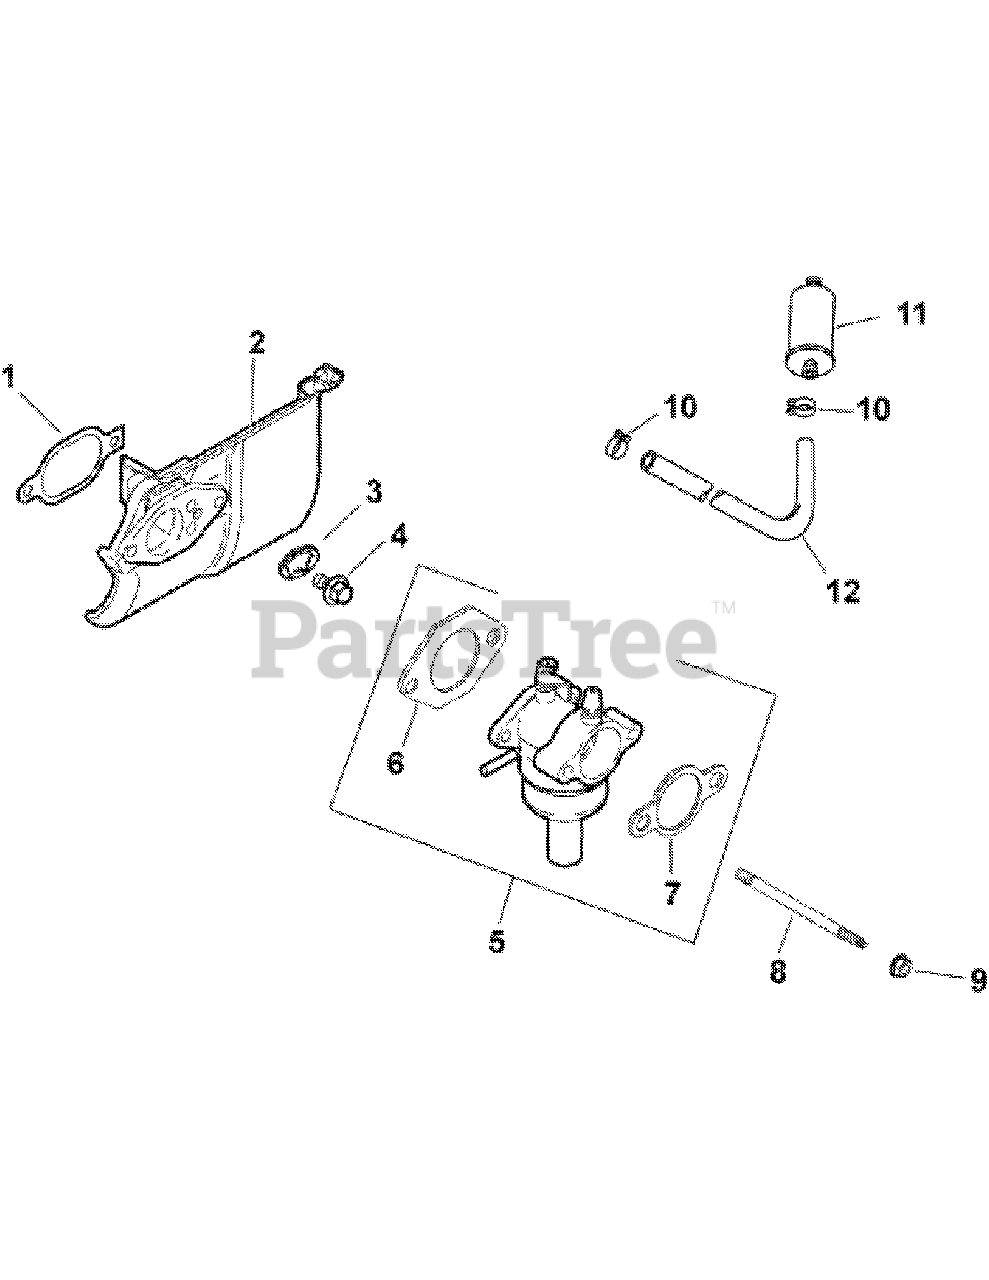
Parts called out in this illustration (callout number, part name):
2	KIT
3	WASHER, INT TOOTH LOCK 1/4"
4	SCREW, FLG M6x1.0x20
5	KIT, CARBURETOR W/GASKETS
6	GASKET, AIR CLEANER BASE
7	GASKET, CARBURETOR
8	STUD, M6X1.0X100
9	NUT, FLG M6X1.0
10	CLAMP, SPRING HOSE 1/2"
12	LINE, FLEXIBLE FUEL - 7"
